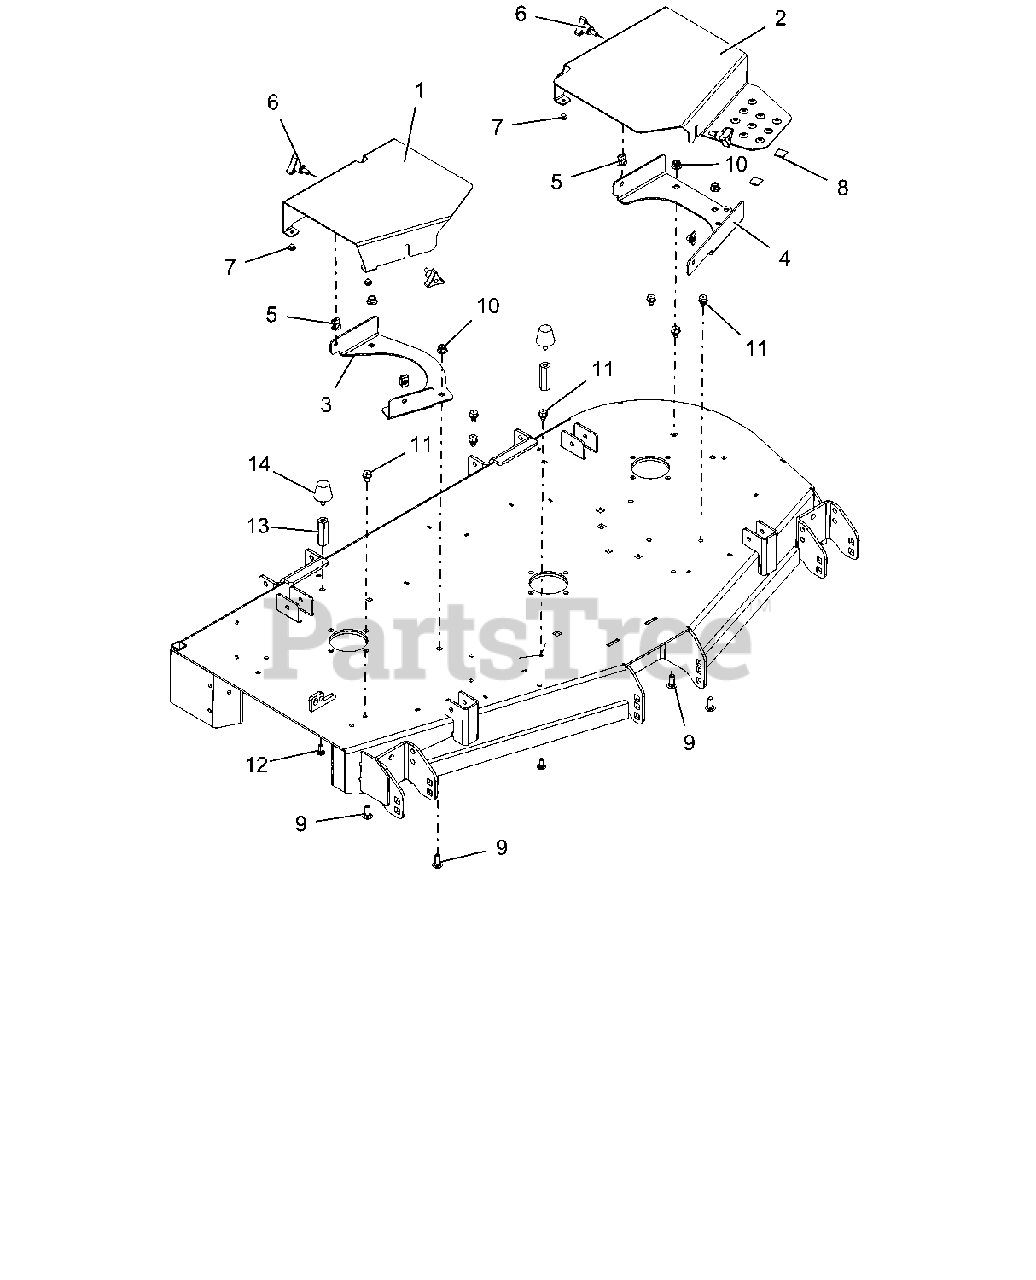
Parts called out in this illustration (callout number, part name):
1	GUARD, RH PT 400/200 BELT (RED)
2	GUARD, LH PT400/200 BELT
3	BRKT, BELT GUARD RH MOUNTING (RED)
4	BRKT, BELT GUARD LH (RED)
5	NUT-CLIP RETAINER 5/16-18X.56
6	KNOB, WING STUD .312-18X.75
7	BUMPER GROMMET .125 X .25 REV
9	BLT-RDHDSQNK .38-16X1.00 G5 YWZC
10	NUT-LK-NYL-FLG .38-16 YWZC
11	SCR-TAP .38-16X.50 HWH TR YWZ
12	BLT, RDHDSQNK .31-18X.75 LOCTITE
13	NUT, .31-18 X 2.25 LG COUPLING
14	BUMPER, RUBBER CONE STUD MOUNT
